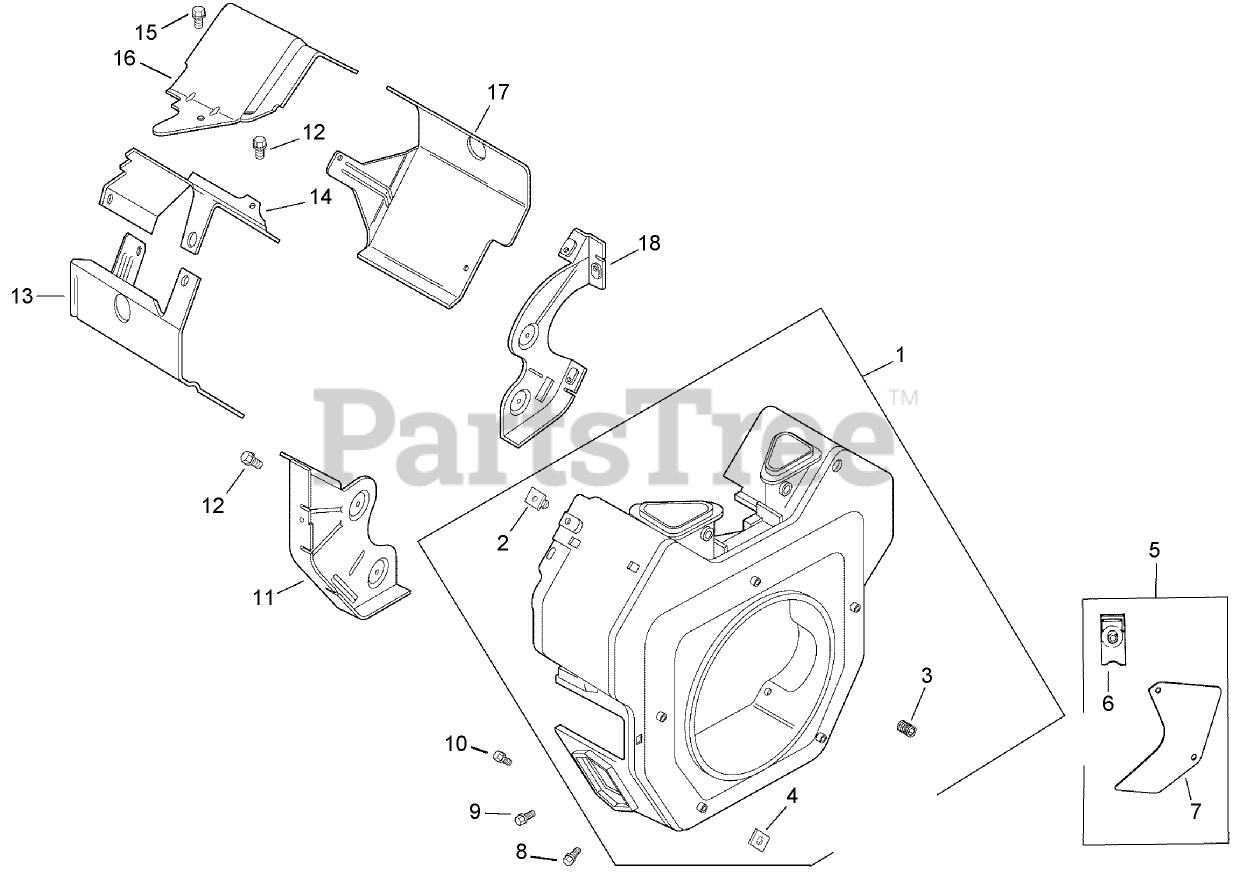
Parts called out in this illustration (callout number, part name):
1	Blower Housing ASM (Includes 2-5)
2	NUT-PLASTIC
3	Screw-Set (10-24X.25)
4	Nut-Plastic
5	Clip-Mounting
6	Access Cover Kit (Includes 6, 7)
7	Panel-Access
8	Screw-Hex Flange, Heavy (M5x0.8x16)
9	SCREW-FLANGE, THREAD FORMING (M5X0.8X16)
10	SCREW-FLANGE, THREAD FORMING (M5X.8X20)
11	Plate-Backing (No. 2 Side)
12	SCREW-FLANGE, THREAD FORMING (M6X1.0X16)
13	Baffle-Barrel, Cylinder (No. 2 Side)
14	Baffle-Valley (No. 2 Side)
15	SCREW-HHFTF (M5X.80X10)
16	BAFFLE-VALLEY (No. 1 SIDE)
17	Baffle-Barrel, Cylinder (No. 1 Side)
18	Plate-Backing (No. 1 Side)
